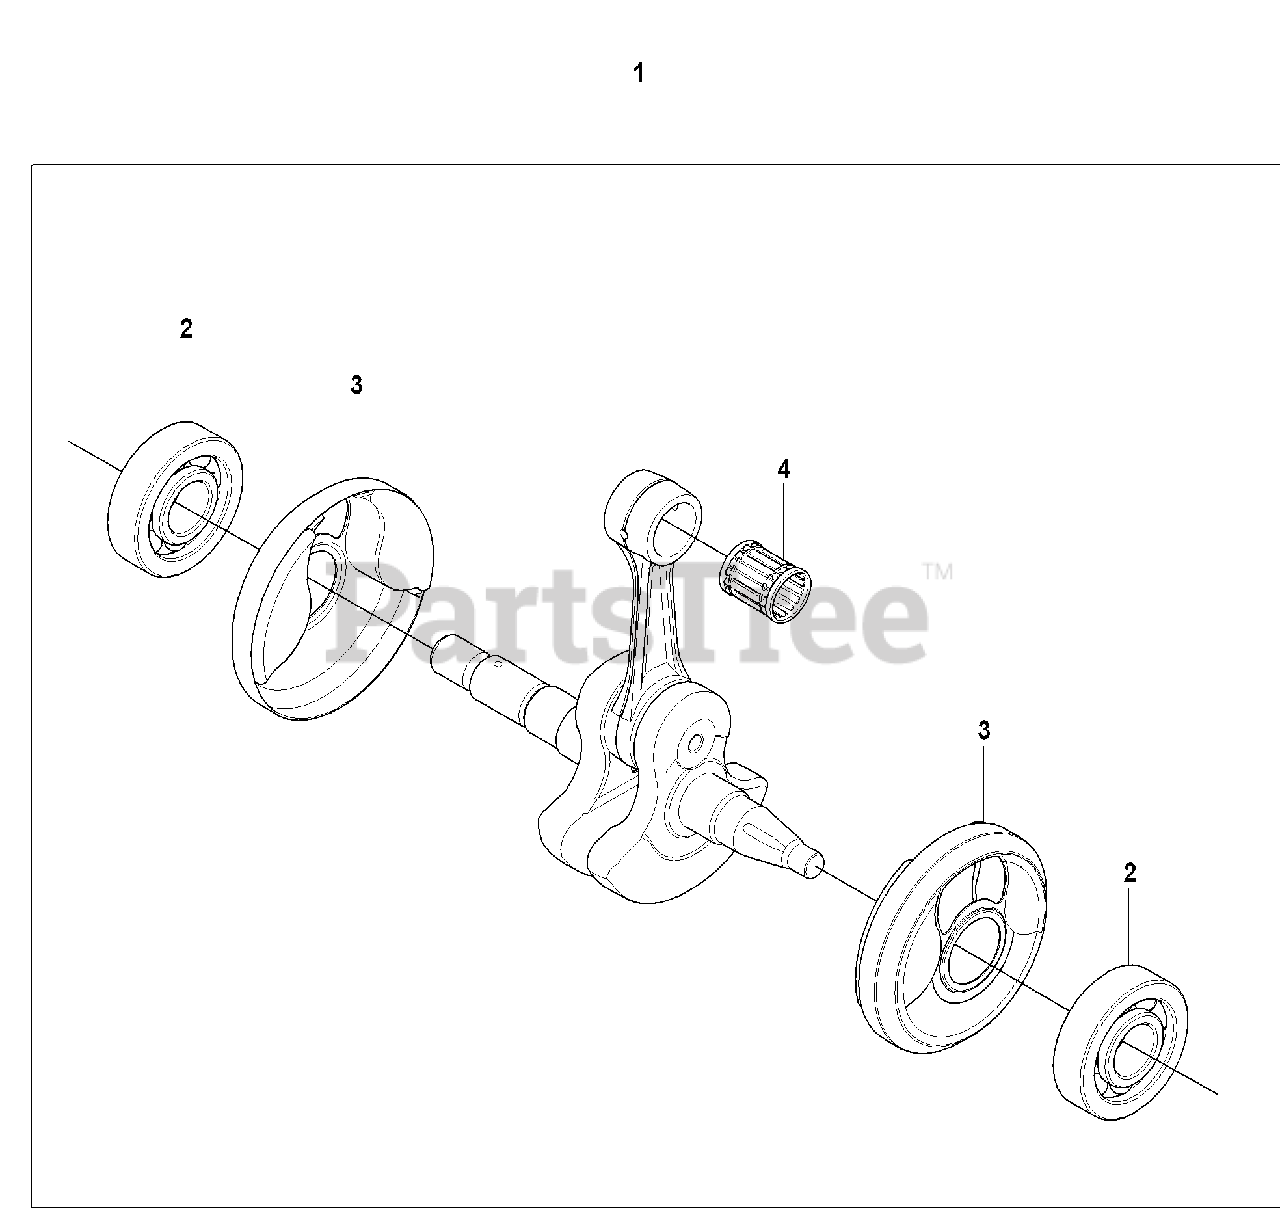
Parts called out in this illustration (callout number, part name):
1	CRANKSHAFT ASSY
2	BALL BEARING
4	NEEDLE BEARING
